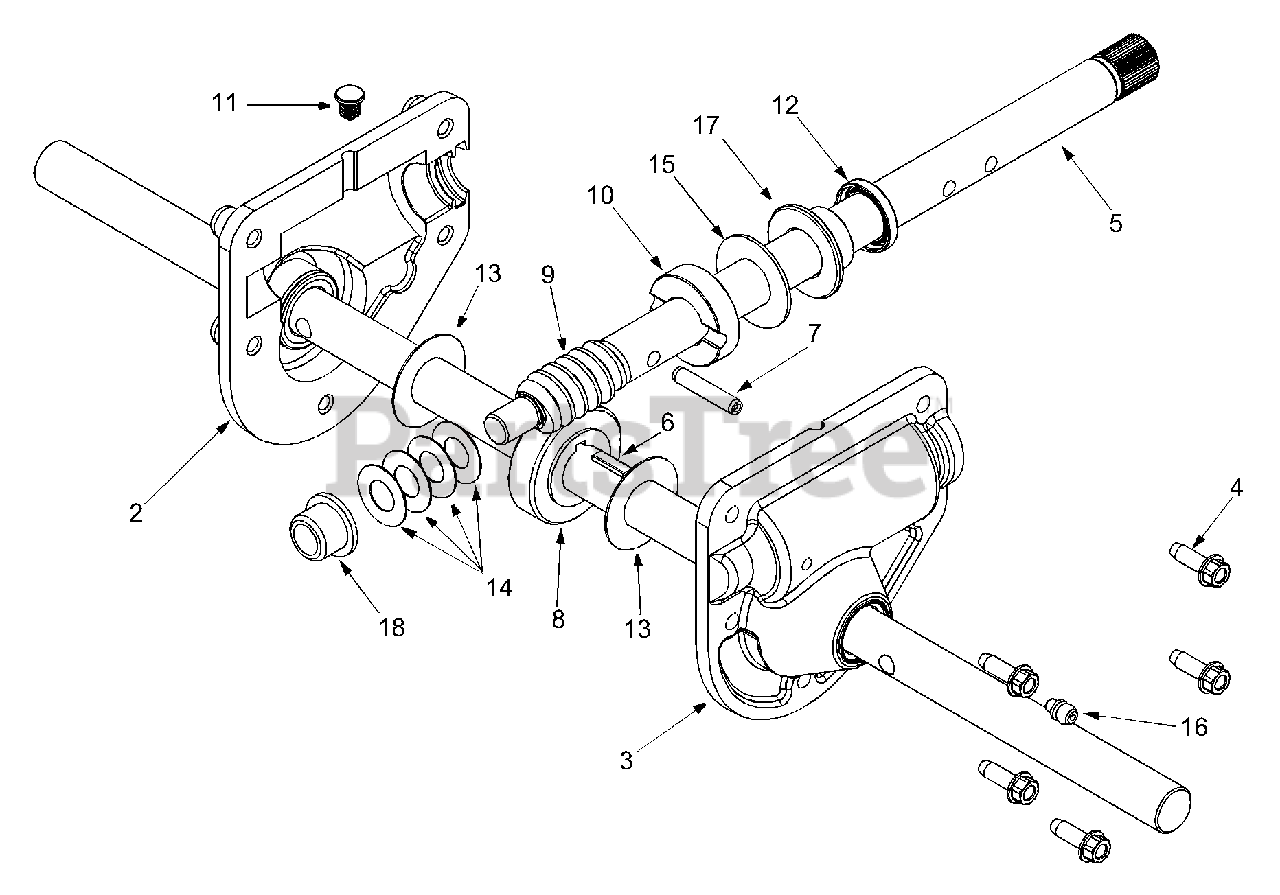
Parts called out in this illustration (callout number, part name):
1	Auger Gearbox Ass'y Comp.
2	Housing Assembly, RH
3	Housing Assembly, LH
4	Screw, 1/4-20 x .75
5	Worm Shaft .75 O.D.
6	Hi-Pro Key
7	Spirol Pin
8	Worm Gear 20T
10	Thrust .75 I.D. x .415 O.D.
11	Plug 1/4 x .437
12	Oil Seal .75 I.D. x 1.73 O.D.
13	Fl-Wash. .760 I.D. x 1.5 O.D.
14	Fl-Wash. .508 I.D. x 1.0 O.D.
15	Fl-Wash. .76 I.D. x 1.50 O.D.
16	Lube Fitting 3/16 Drive
17	Flange Bearing
18	Flange Bearing
